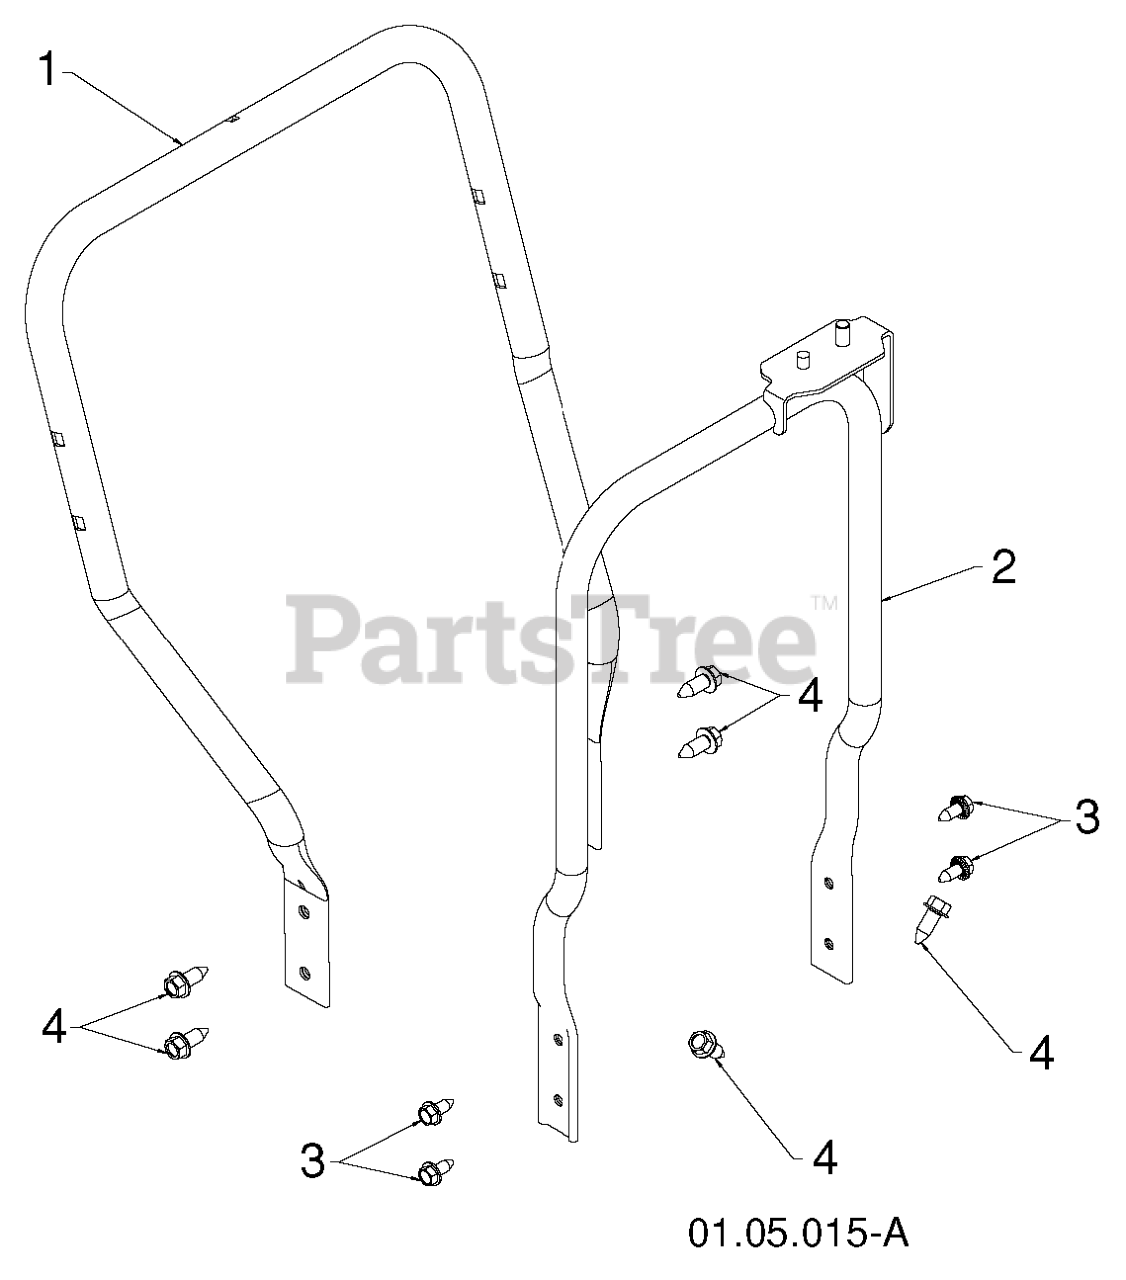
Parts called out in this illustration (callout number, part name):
1	TUBE. LOWER.PNT
2	SUPPORT.WELDMENT.ROTATOR.BLACK
3	BOLT.HEX.HD.WASHER.5/16-18X.75
4	SCREW 3/8-16X1
